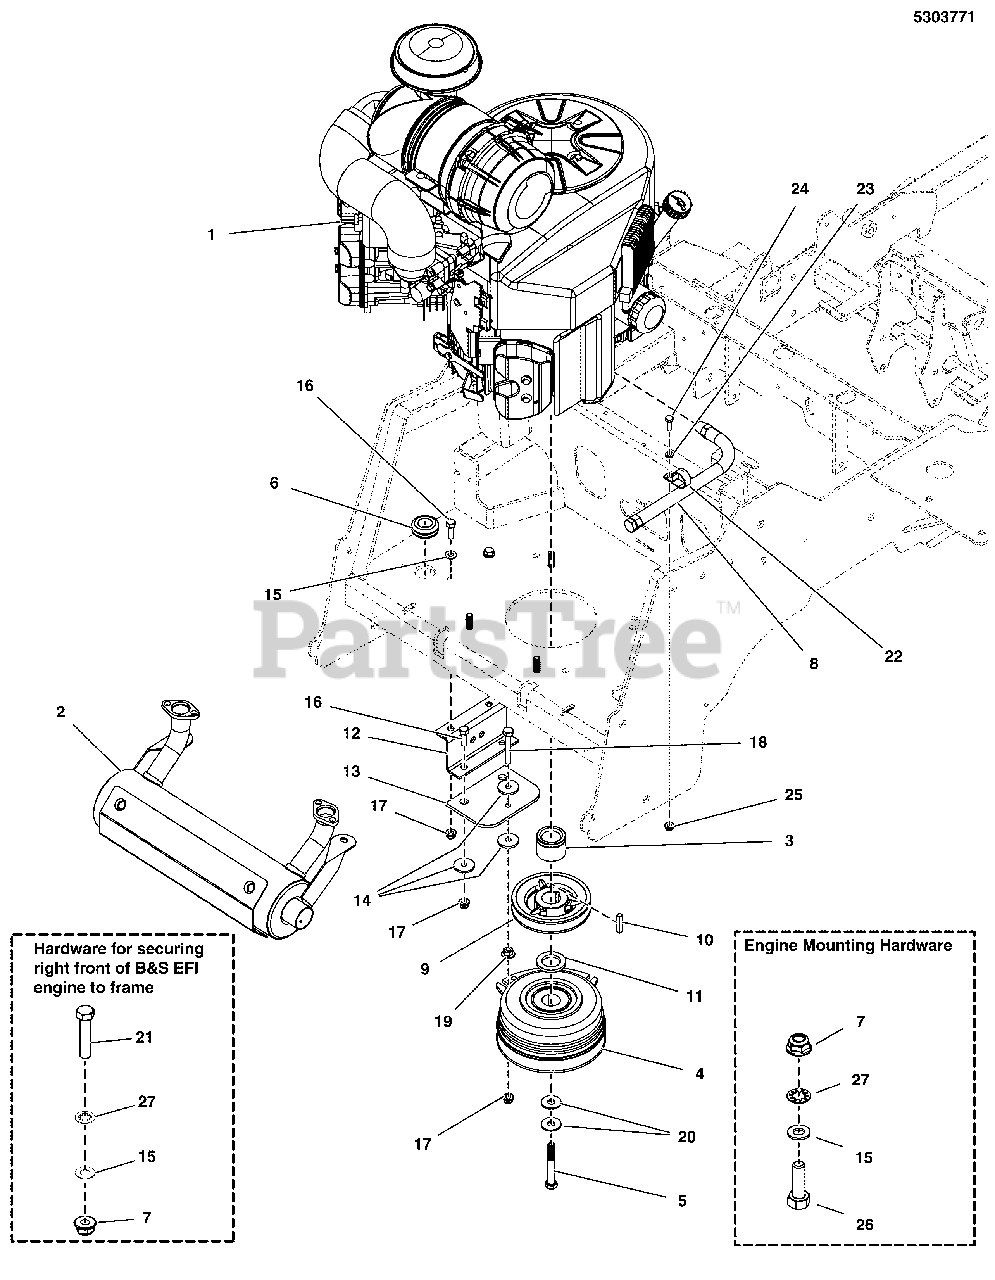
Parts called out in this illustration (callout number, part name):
1	ENGINE, 28HP BRIGGS VANGUARD, EFI
2	MUFFLER
3	SPACER, 1.13 X 1.75 X 1.35, CZ
4	CLUTCH,5218-221, WARNER
5	BOLT, CRANKSHAFT, 7/16-20 X 3, GD8
6	GROMMET, 7/8"ID, 1/4" THICK STK
7	NUT, 5/16-24, TOP LOCK FLANGE, GD8 PHOS
8	HOSE, OIL DRAIN
9	PULLEY, 4.75 OD X 1-1/8 BORE, BC-48
10	KEY, 1/4 SQ X 1-1/4
11	SPACER, 1.13 X 1.75 X .25
12	ANCHOR, CLUTCH, IS600-IS700 - BLK
13	CLUTCH ANCHOR PAD
14	WASHER, .34 X 1.25 X 10 GA
15	WASHER, 5/16 SAE
16	BOLT, 5/16-18 X 1 GD5 YZ
17	NUT, 5/16-18 HEX NYLOCK FLANGE
18	BOLT, 5/16-18 X 2-1/4 GD5 TFL, ZN
19	NUT, 5/16-18 HEX SERRATED FLANGE (LARGE)
20	BELLEVILLE WASHER 1.1875 X .442 X .089
21	BOLT-HEX, 5/16-24 X 1-1/2", GD8, PHOS
22	CLAMP, VINYL INSULATED
23	WASHER, 1/4 SAE
24	BOLT, 1/4-20 X 3/4 GD5 YZ
25	NUT, 1/4-20 HEX SERR. FLANGE
26	BOLT, 5/16-18 X 1-3/4 GD8, PHOS
27	WASHER, 5/16 INT. TOOTH LOCK
